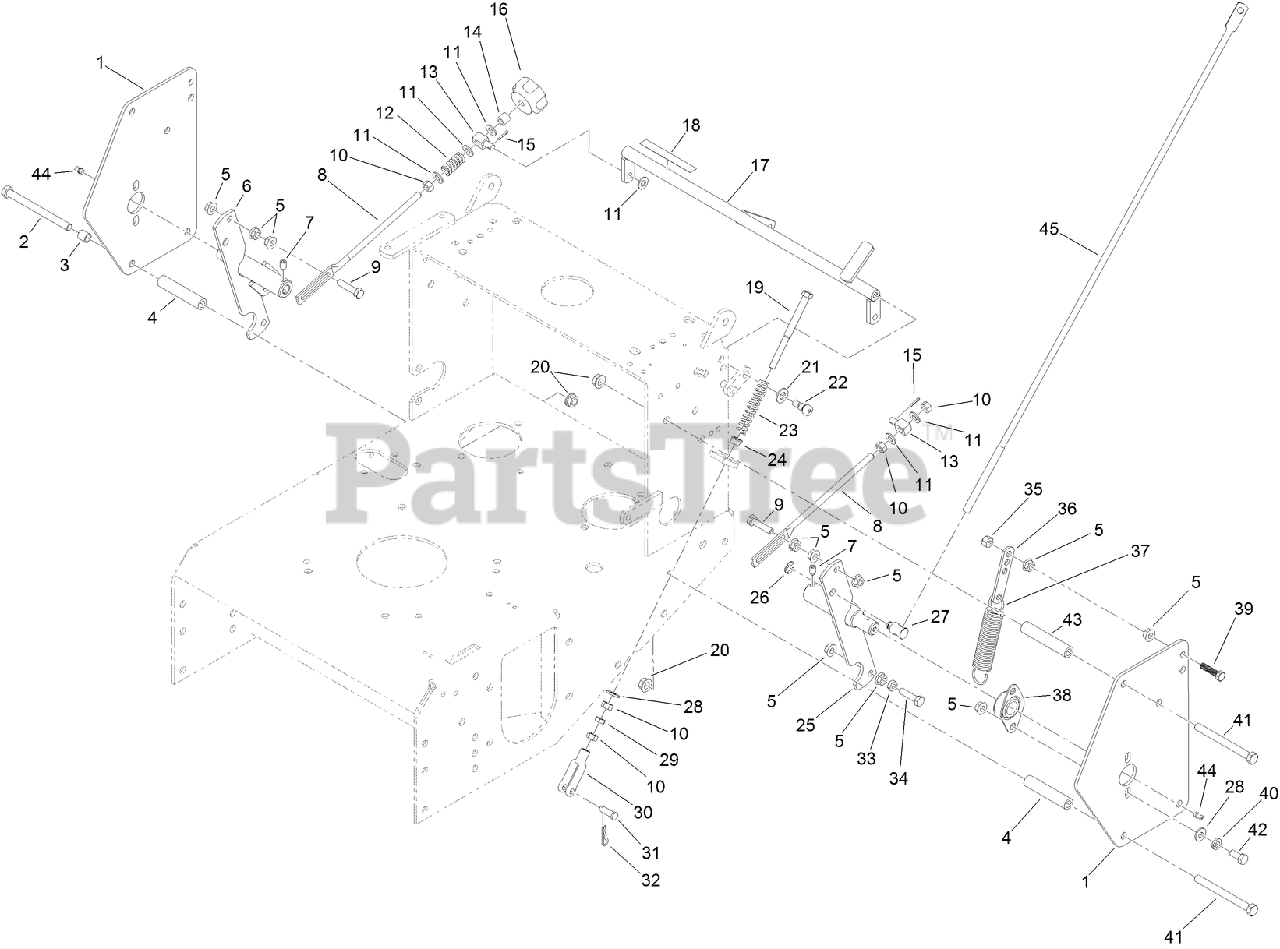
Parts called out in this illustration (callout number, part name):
1	SHIELD-CONTROL
2	SCREW-HH
3	SPACER-TUBE, PUMP LINK
4	SPACER-SHIELD
5	NUT-HF
6	SHAFT-CONTROL, RH
7	SCREW-SET
8	LINK-CONTROL, SPEED
9	SCREW-HH
10	NUT-HEX
11	WASHER-PLAIN
12	SPRING-COMPRESSION
13	SWIVEL-ADJUSTABLE, SHORT
14	SPACER
15	PIN-COTTER
16	KNOB-TRACKING
17	Crank-Control, Speed
18	DECAL-TRACKING
19	BOLT-RETURN, NEUTRAL
20	NUT-HHF, WHIZ
21	WASHER-FLAT
22	SCREW-HSH
23	SPRING-RETURN, NEUTRAL
24	BUSHING-FLANGED
25	Shaft-Control, LH
26	RING-RETAINING
27	SWIVEL-LEVER, DRIVE
28	WASHER-FLAT
29	NUT-JAM
30	YOKE-ADJUSTABLE
31	PIN-CLEVIS
32	PIN-COTTER
33	NUT-JAM
34	SCREW-HH, SPECIAL
35	NUT-LOCK, NI
36	TAB-SPRING, EXTENSION
37	SPRING-EXTENSION
38	BEARING-FLANGE, SIDE
39	BOLT-TAP, HH
40	WASHER-LOCK
41	SCREW-HH
42	SCREW-HH
43	Spacer-Shield
44	FITTING-GREASE
45	ROD-LEVER, DRIVE
